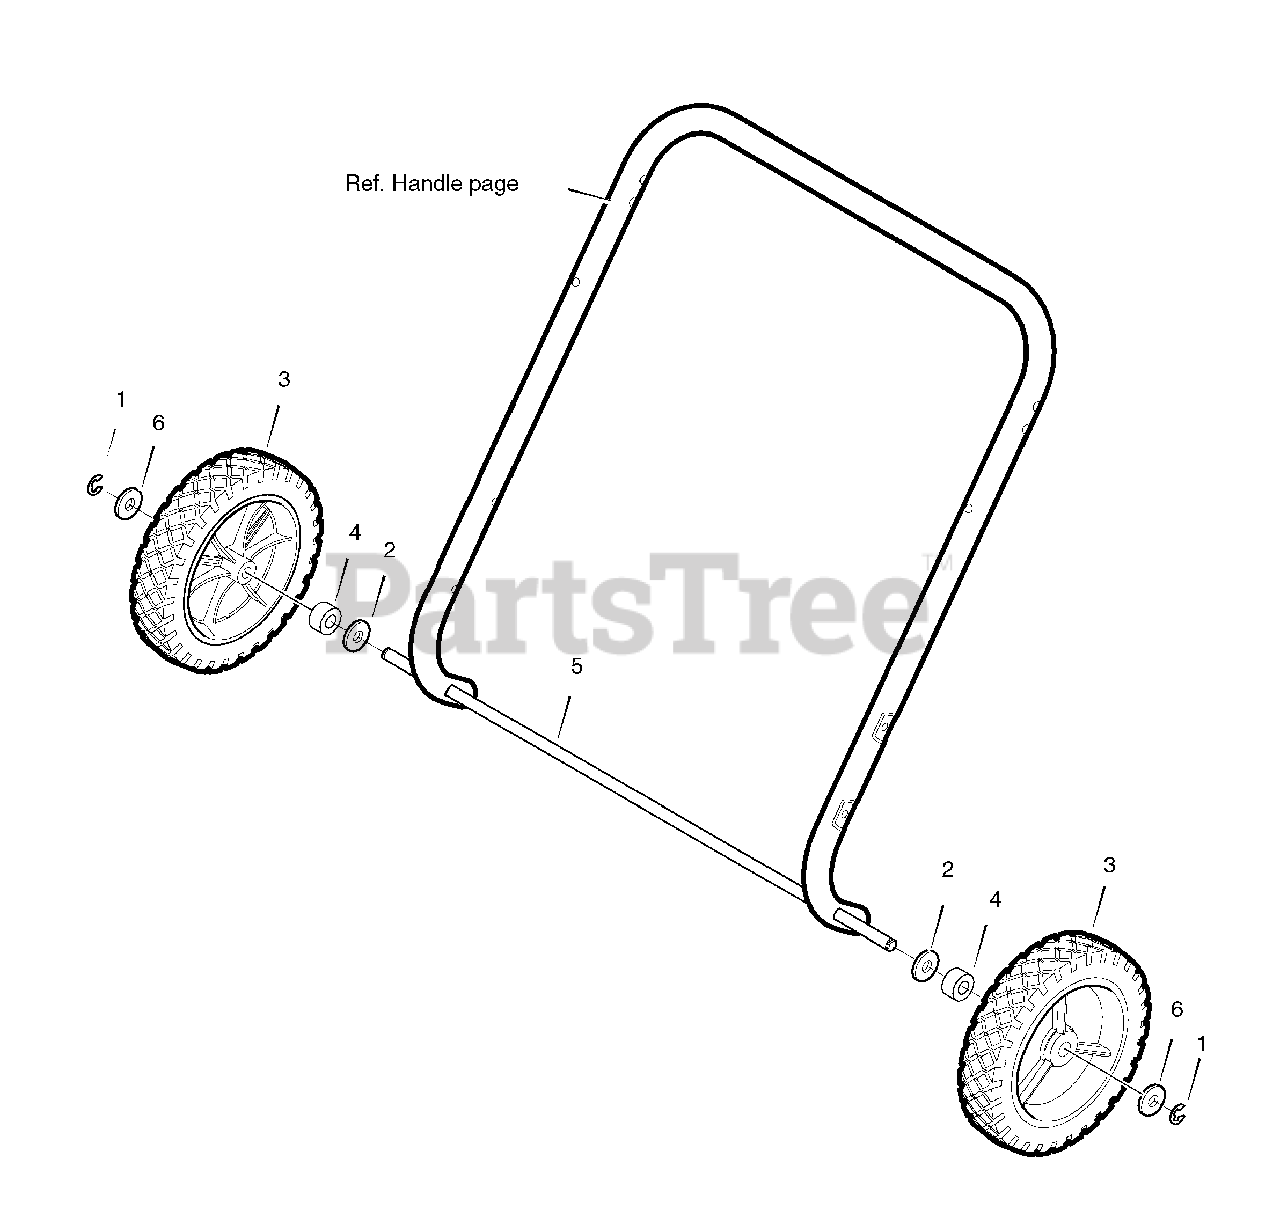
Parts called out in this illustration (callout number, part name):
1	RETAINER, E-Ring
2	WASHER, Flat 13-32 x 13/16
3	WHEEL AND TIRE 7" x 1.50"
4	SPACER, Sleeve 13/32 x 5/8
5	ROD, Axle, Single Stage, 22"
6	WASHER, Flat 25/64 x 1.00 x 1/8
